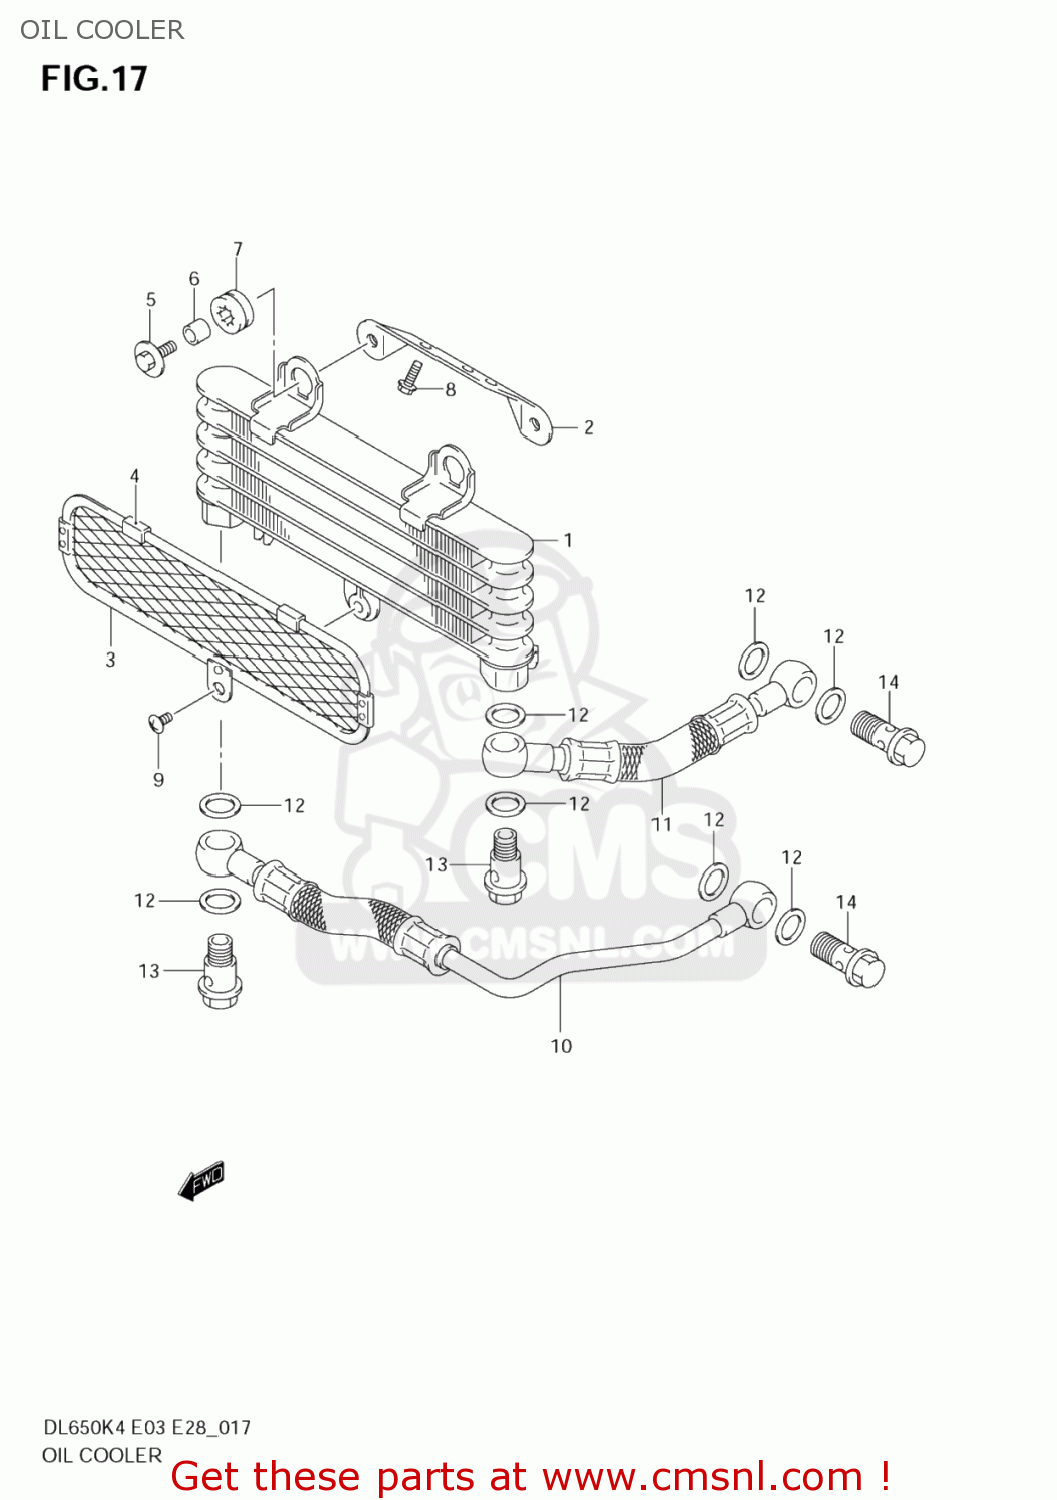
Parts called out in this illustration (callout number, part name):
1	COOLER ASSY,OIL
2	BRACKET,OIL COOLER
3	GUARD COMP,OIL
4	PROTECTOR,CTR
5	BOLT(6X20)
6	SPACER(6.5X10X10)
7	CUSHION
8	BOLT
9	SCREW
10	HOSE,OIL COOLER,R
11	HOSE,OIL COOLER,L
12	GASKET(14X20X1.5) (NAS)
13	BOLT UNION
14	BOLT UNION
